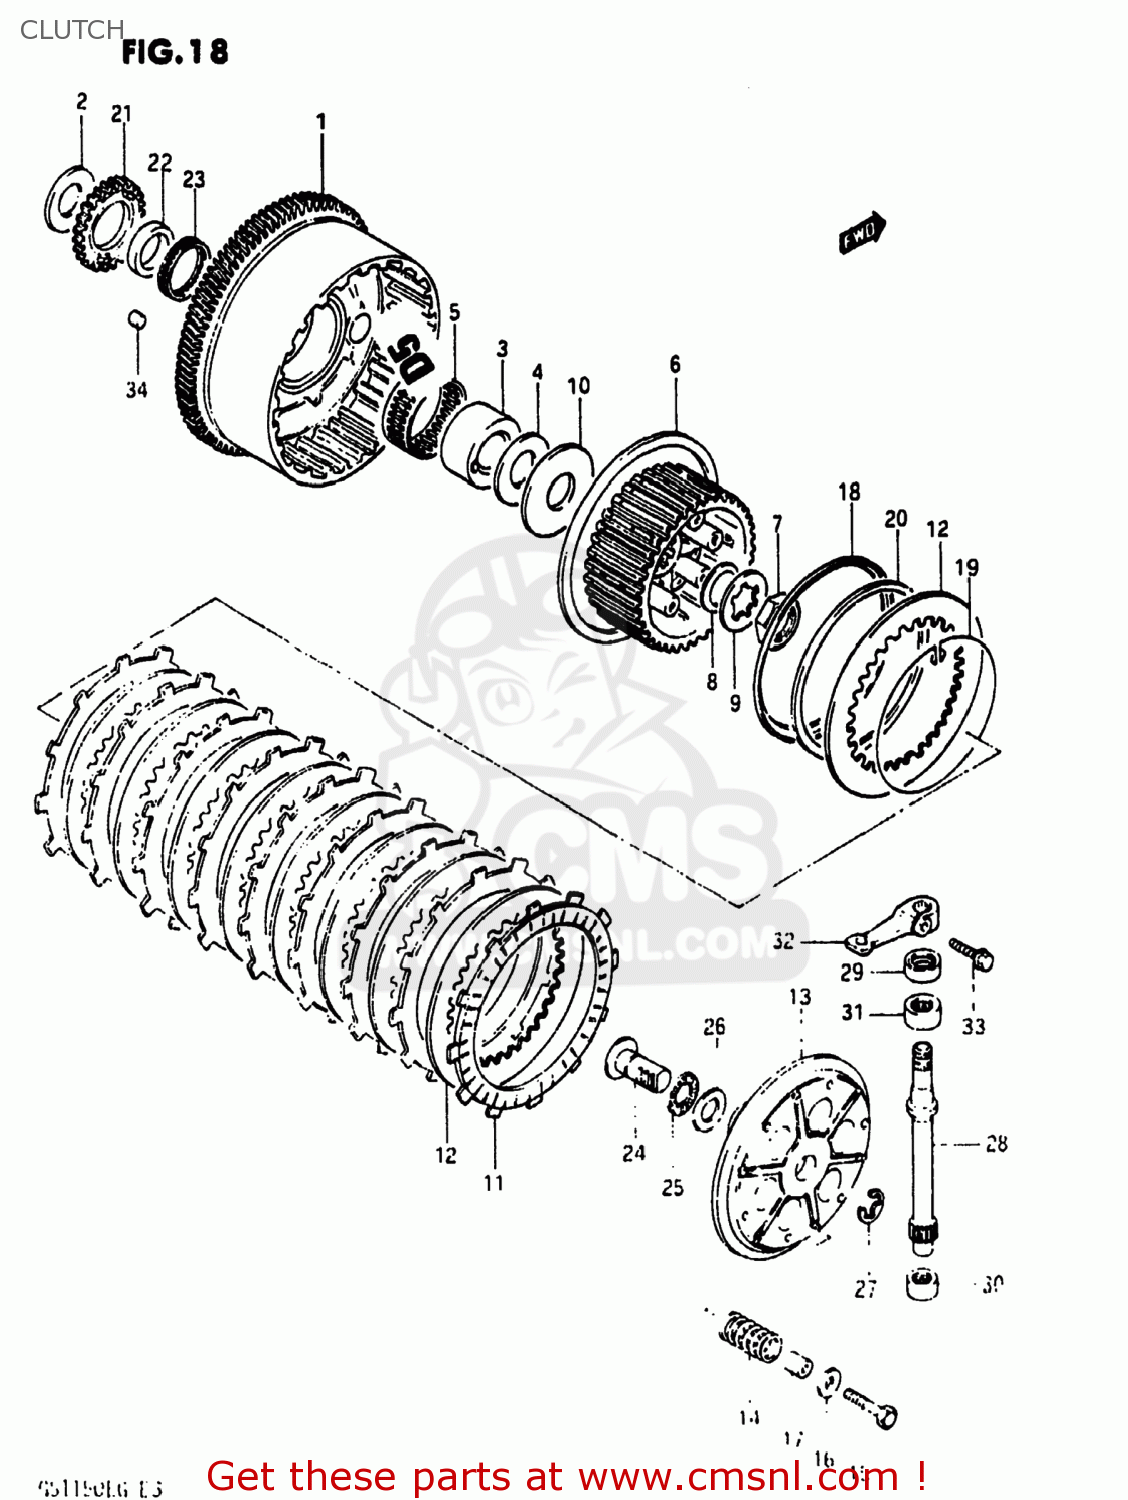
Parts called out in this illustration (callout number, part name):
1	GEAR ASSEMBLY,PRIMARY DRIVE
2	WASHER(25X50X2.5)
3	SPACER
4	SHIM(T:1.00)
5	BEARING(51X56X28)
6	HUB,CLUTCH SLEEVE
7	NUT
8	WASHER
9	WASHER,LOCK
10	WASHER(25X66X3.5)
11	PLATE,CLUTCH DRIVE (MCA)
12	PLATE,CLUTCH DRIVEN (NAS)
13	DISC,CLUTCH PRESSURE
14	SPRING
15	BOLT
16	WASHER
17	SPACER
18	SEAT,WAVE WASHER
19	RING,STOPPER
20	WASHER
21	GEAR,ENG OIL PUMP DRIVE(NT:34)
22	SPACER,OIL PUMP DRIVE GEAR
23	BEARING(36X40X10)
24	RACK,CLUTCH RELEASE
25	BEARING(15X28X2)
26	WASHER
27	E RING 12MM
28	PINION,CLUTCH RELEASE
29	OIL SEAL
30	BEARING(12X19X12)
31	BEARING(15X22X12)
32	ARM,CLUTCH RELEASE
33	BOLT (6X20)
34	CUSHION,PRIMARY DRIVEN GEAR
